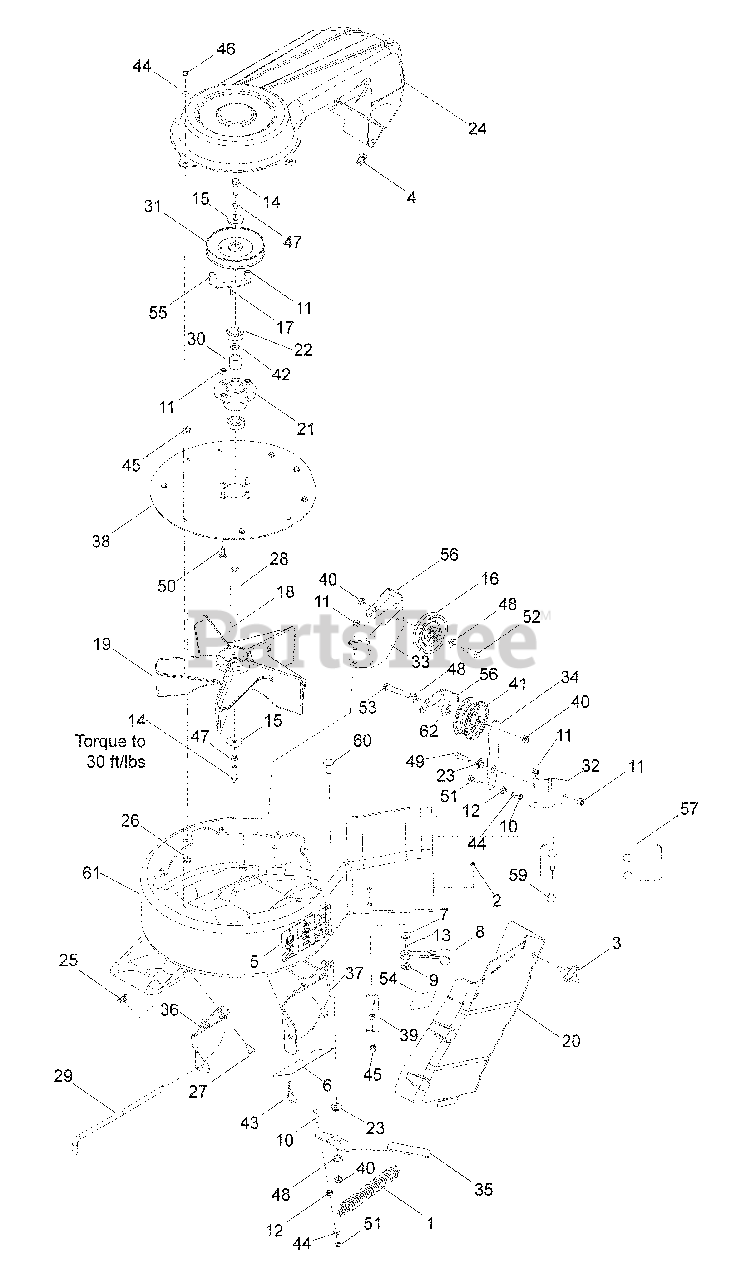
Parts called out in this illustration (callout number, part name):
1	TRACTION SPRING
2	SCREW 10-24 x .625 RD
3	KNOB W/STUD
4	RETAINER U TYPE
5	DECAL, WARNING
6	DECAL, SEVERING
7	WASHER 3/16 x ¾ x 16 GA
8	LATCH, HOOD
9	WELD NUT, PLATED
10	NUT ¼-20 HEX NYLOC
11	NUT 5/16-18 HEX NYLOC
12	NUT ¼-20 HEX FLANGE
13	WASHER 3/16 LOCK
14	BOLT, HEX 3/8-24 x 1¼ GR 8
15	WASHER, HARDENED
17	KEY 3/16 x ½
18	KEY 3/16 x 1½
20	COVER, BELT
21	HUB, BEARING
24	COVER, OUTER PULLEY
25	NUT 5/16-18 TEE
26	NUT ¼-20 TEE
27	HCS 5/16-18 x ½
28	SHAFT, IMPELLER
32	MOUNT, IDLER, UPPER
33	MOUNT, IDLER, LOWER
34	ARM, IDLER
35	ARM, TENSION
36	BRACKET, MOUNT, FRONT
37	BRACKET, MOUNT, REAR
38	PLATE, OUTER
40	NUT 3/8-16 HEX JAM NYLOC
41	PULLEY, IDLER
43	HAIRPIN COTTER, 1/8 x 1¾
44	WASHER ¼ FLAT SAE
45	SCREW ¼ x 3/8 THRD FRM
46	HCS ¼-20 x ½
47	WASHER 3/8 SPLT LOCK
48	WASHER 3/8 SAE FLT
49	HCS 5/16-18 x 1
50	RHSNB 5/16-18 x ¾
51	HCS ¼-20 x 7/8
52	HCS 3/8-16 x 1½
53	WASHER 5/16 STD FLT
54	DECAL, BELT ROUTING
55	KEEPER, BELT, OUTER
56	KEEPER, BELT, REAR
57	PLATE, BACKING
58	PLATE, BACKING
59	RHSNB 5/16-18 x 1
60	RHSNB 3/8-16 x 1
61	HOUSING w/DECALS
62	SPACER, BELT RETAINER
